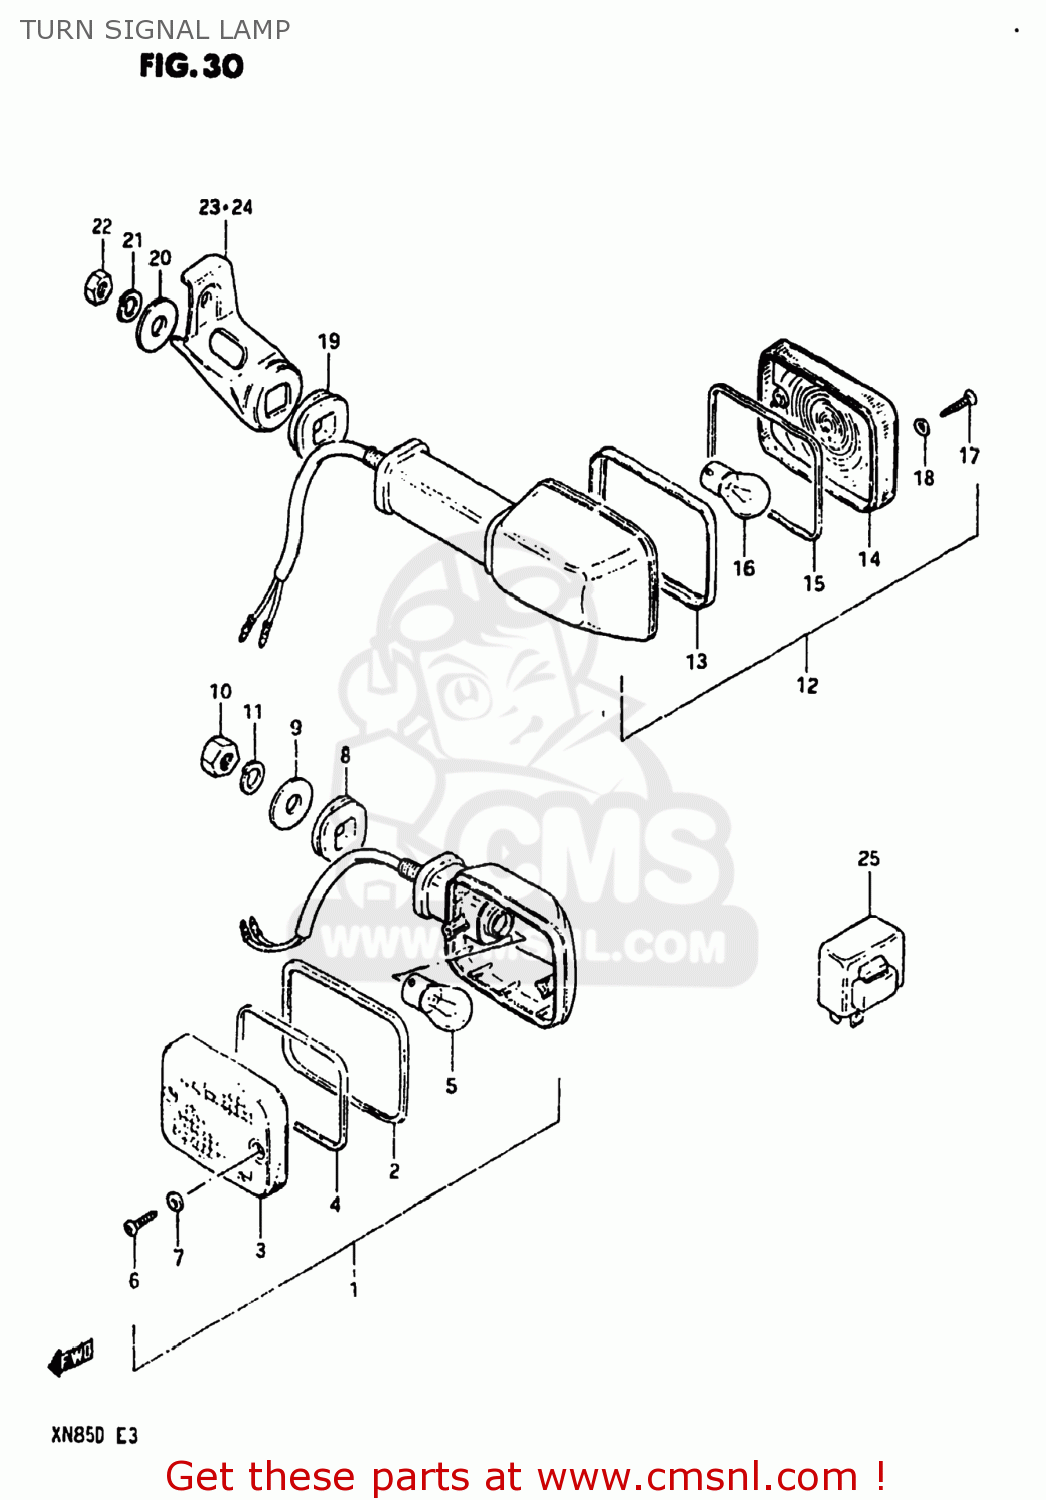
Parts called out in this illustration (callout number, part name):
1	LAMP ASSEMBLY,FRONT TURN SIGNAL
2	RIM
3	LENS
4	GASKET (NAS)
5	BULB(12V23W,STANLEY,A4577A)
6	SCREW
7	GASKET (NAS)
8	CUSHION
9	WASHER (10.5X30X2.3)
10	LOCK WASHER
11	NUT
12	LAMP ASSEMBLY,FRONT TURN SIGNAL
13	RIM
14	LENS
15	GASKET (NAS)
16	BULB(12V23W,STANLEY,A4577A)
17	SCREW
18	GASKET (NAS)
19	CUSHION
20	WASHER (10.5X30X2.3)
21	LOCK WASHER
22	NUT
23	BRACKET,REAR TURN SIGNAL
24	BRACKET,REAR TURN SIGNAL
25	RELAY,TURN SIGNAL
